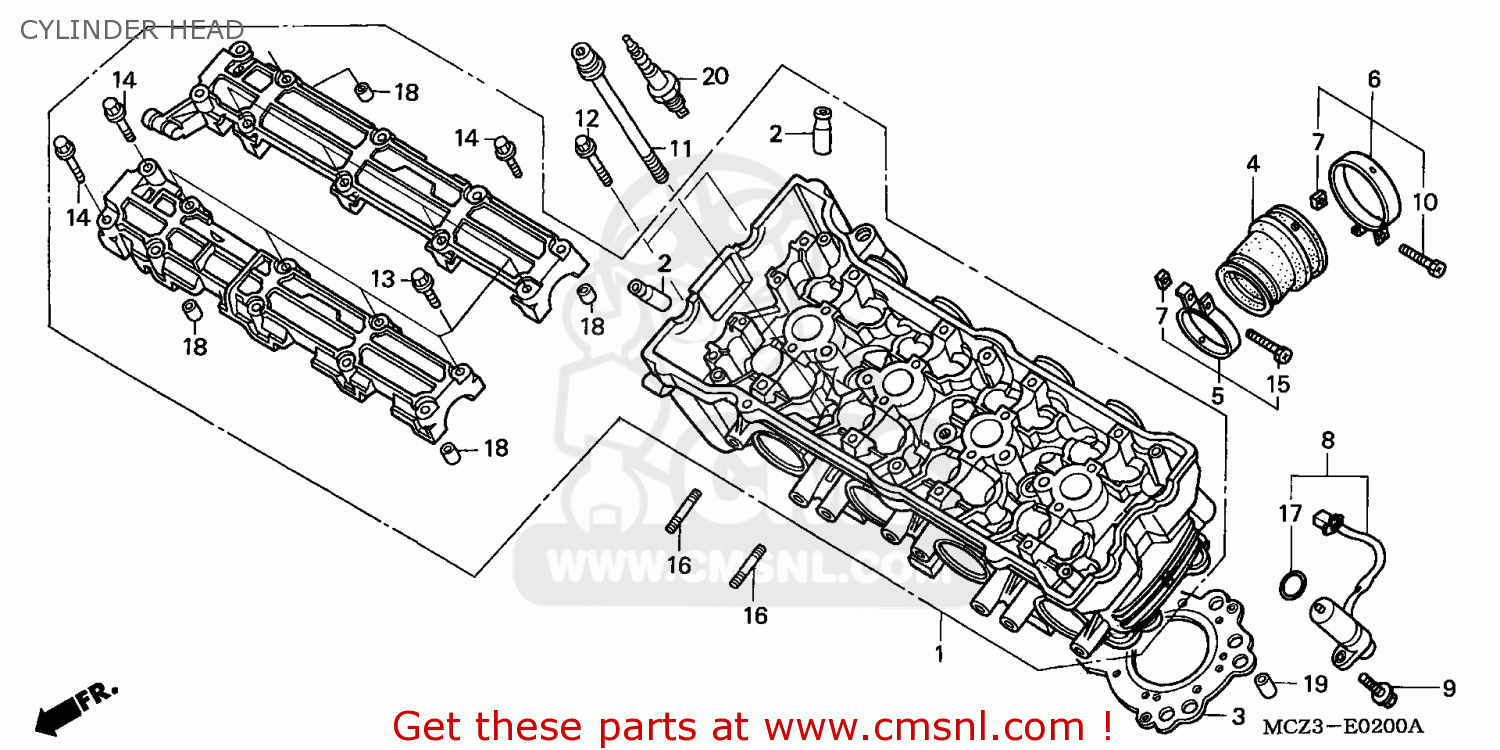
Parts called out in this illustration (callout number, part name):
1	HEAD ASSY,CYLINDE
2	GUIDE,VALVE(OUTER
3	GASKET,CYLINDER H (NAS)
4	INSULATOR,THROTTL
5	BAND,INSULATOR A
6	BAND,INSULATOR
7	NUT,SQUARE,5MM
8	PULSER ASSY CAM
9	BOLT,FLANGE 6X18
10	BOLT,RECESSED,5X2
11	BOLT,SOCKET 9X95
12	BOLT,FLANGE,SH,6X
13	BOLT,FLANGE 6X37
14	BOLT,FLG.,6X45.5
15	BOLT,RECESSED,5X2
16	BOLT STUD 8X24
17	O-RING 16X2.1
18	PIN,DOWEL,8X20
20	PLUG,SPARK(CR8EH9
